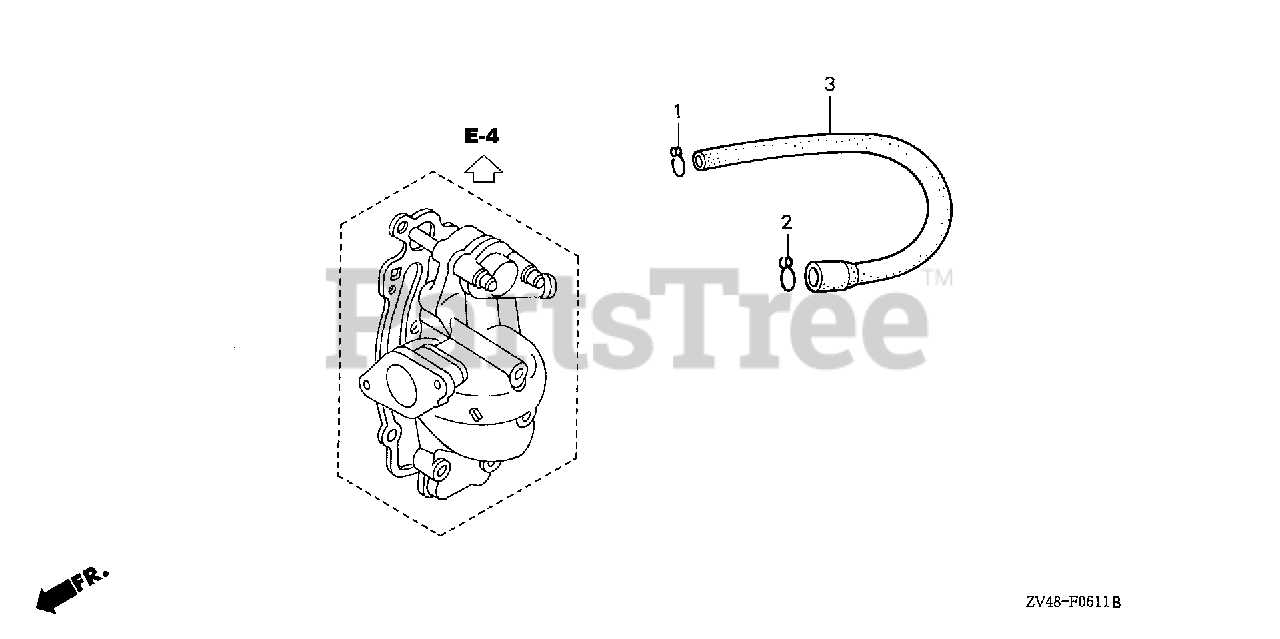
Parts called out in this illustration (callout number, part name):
1	CLIP, TUBE (B12.5)
2	CLIP, TUBE (B16)
3	TUBE, WATER RETURN (A)
